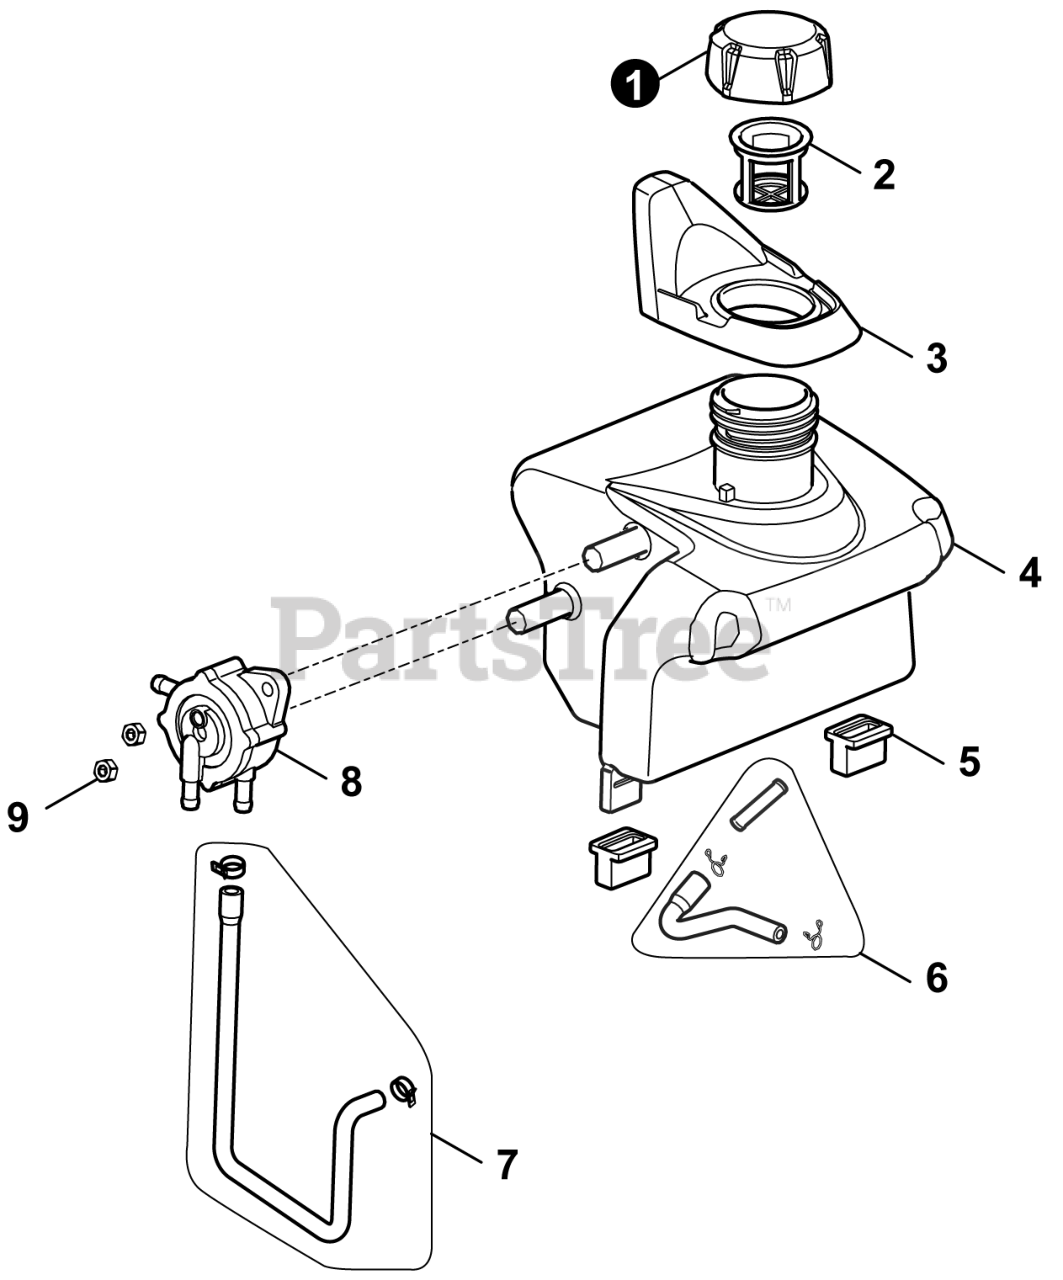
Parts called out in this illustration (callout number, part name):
1	CAP, FUEL
2	STRAINER, FUEL
3	COVER, SPILL
4	TANK, FUEL
5	SLEEVE, FUEL TANK RUBBER
6	HOSE, FUEL
7	HOSE, FUEL
8	PUMP ASSY, GASOLINE
